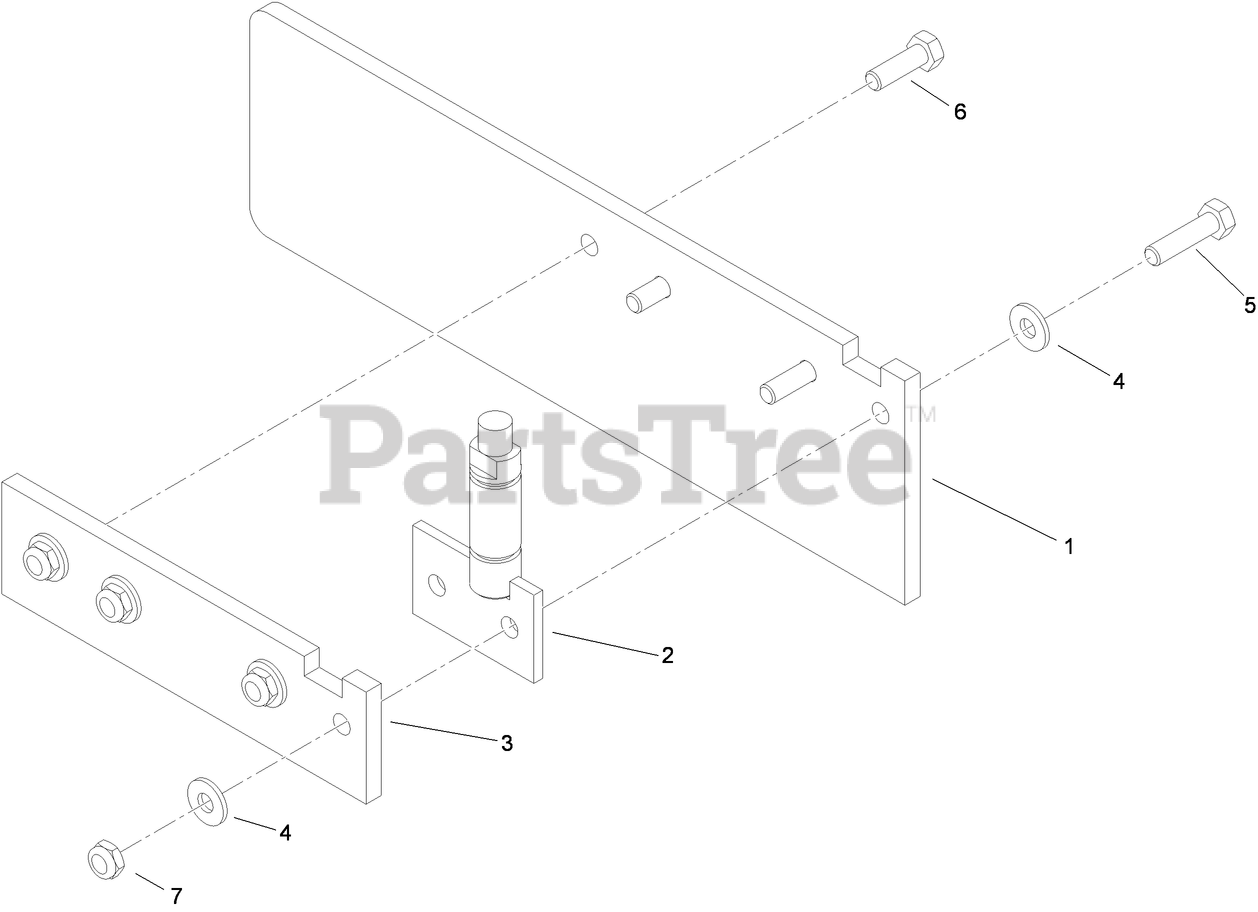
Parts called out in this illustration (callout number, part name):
1	GATE-CHUTE, RUBBER
2	HINGE-GATE
3	DOOR-SUPPORT
4	WASHER-FLAT
5	SCREW-HH
6	SCREW-HH
7	NUT-LOCK, NI
